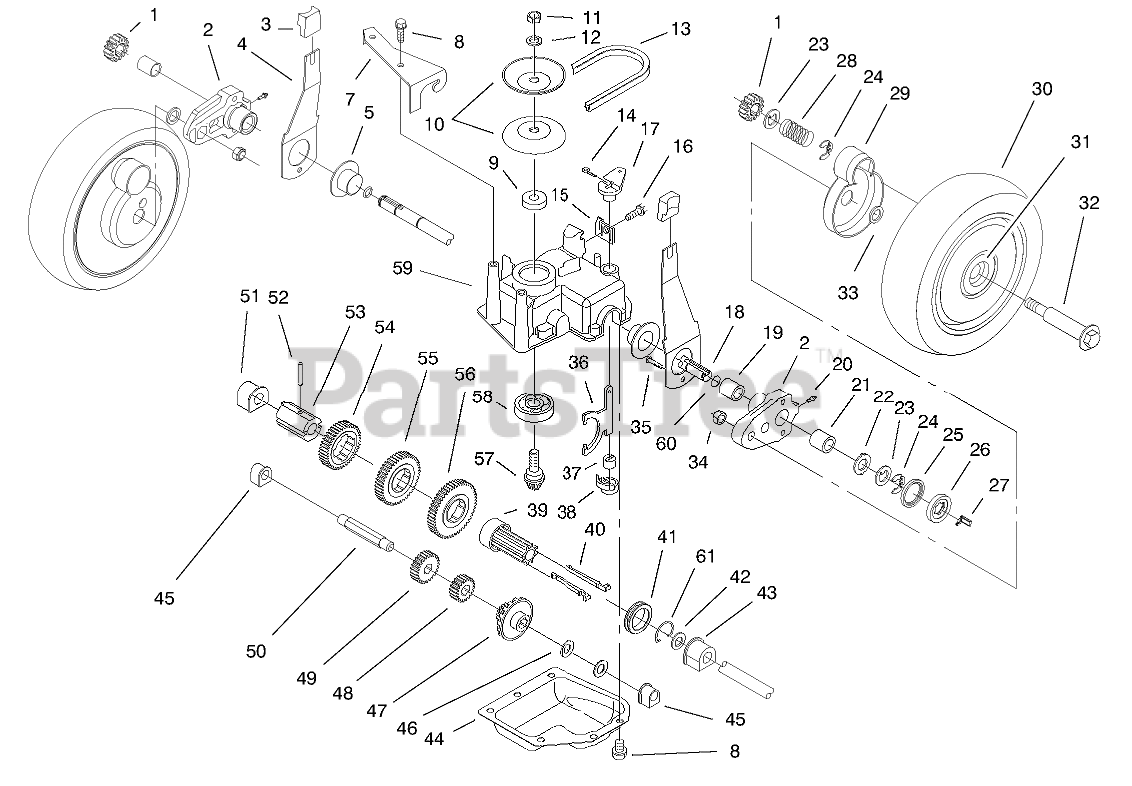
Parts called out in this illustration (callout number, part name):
1	GEAR-PINION
2	Pivot Arm Assembly (Incl. Ref #19, 20, & 21)
3	KNOB-ARM
4	SPRING ARM ASM SP
5	CAP-END
7	Bracket-Guide
8	SCREW-HWHTF
9	SPACER
10	Pulley Half
11	NUT-HEX
12	WASHER-FLAT
13	V-BELT E
14	PIN-COTTER
15	CLAMP-CABLE
16	SCREW-HWHTF
17	LEVER-SHIFT
18	SHAFT-OUTPUT
19	BUSHING
20	FITTING-GREASE
21	BEARING-ROLLER
22	WASHER-ARM, PIVOT
23	WASHER-THRUST, KEYED
24	RING-CLIP, LOCKING
25	RING-FRICTION
26	WASHER-CLUTCH
27	KEY-ROCKING, LH
28	SPRING-COMPRESSION
29	COVER-WHEEL
30	Wheel-Tire & Gear Ass-y (Incl. Ref. #31)
31	BUSHING
32	BOLT-WHEEL
33	SPACER-COVER, WHEEL
34	NUT-LOCK
35	SCREW-HWH
36	YOKE-SHIFT
37	BUSHING-YOKE
38	RETAINER-FORK, SHIFT
39	SLEEVE-KEY, SHIFT
40	KEY-SHIFT
41	COLLAR-SHIFT
42	WASHER-PLAIN
43	BUSHING-OUTPUT
44	Cover-Gearcase
45	BUSHING
46	WASHER-THRUST
47	Gear-Bevel
48	PINION-20T
49	PINION-25T
50	SHAFT-INTERMEDIATE
51	BUSHING
52	PIN-SPRING
53	SLEEVE-GEAR
54	GEAR-39T
55	GEAR-44T
56	GEAR-49T
57	Gear-Pinion
58	BEARING-BALL
59	CASE-GEAR, UPPER
60	O-RING
61	CLIP-SPRING
